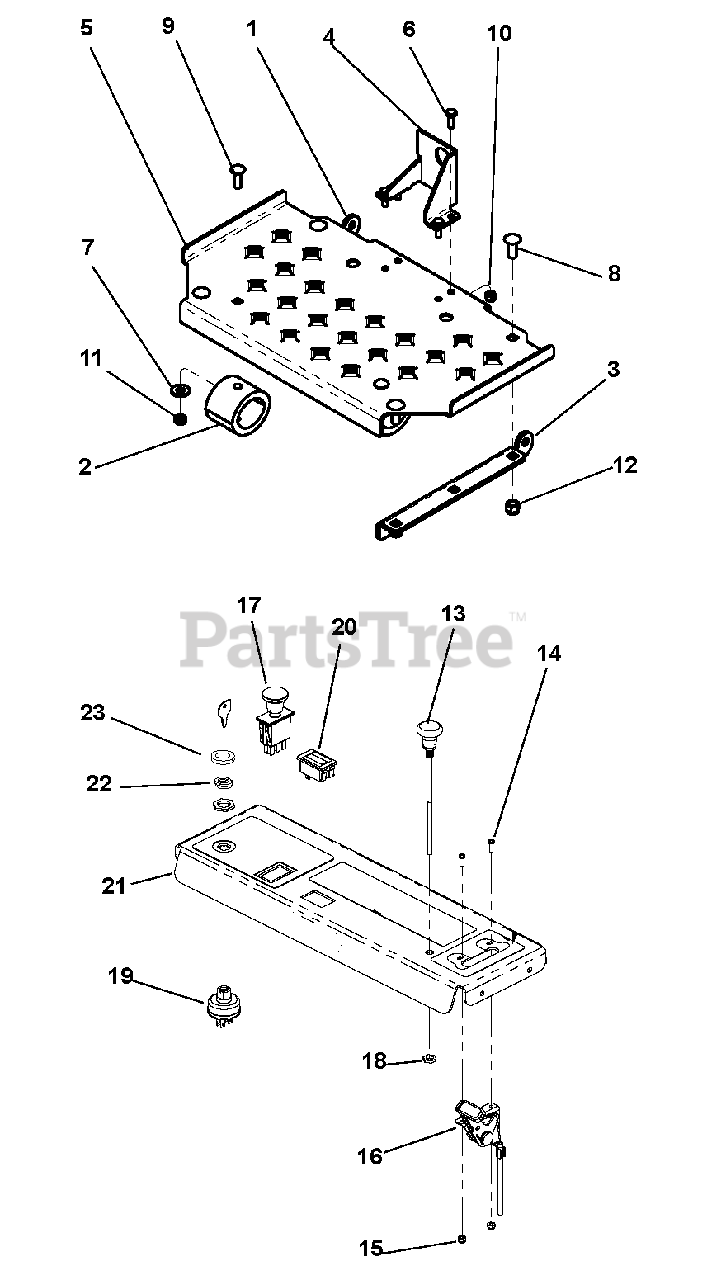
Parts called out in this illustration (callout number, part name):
1	Plate, Platform Tab
2	Bumper, Miner GBR-6
3	Plate, Platform Tab Left Hand
4	Anchor, Operator Presence Control
5	Platform
6	Bolt, Hex .25-20 x .75 Grade 5
7	Washer, Flat-Steel .38 x .875 x .083
8	Bolt, .375-16 x 1.00 Round Head Square Neck Grade 5
9	Bolt, .312-18 x 1.00 Round Head Square Neck Grade 5
10	Nut, Locking-Nylon .25-20
11	Nut, Locking-Nylon .312-18
12	Nut, Locking-Nylon .38-16
13	Cable, Choke
14	Screw, 8-32 x .50 Pan PHL Y
15	Nut, 8-32 Elastic Stop
16	Cable, Throttle
17	Switch, PTO Engagement
18	Nut, Hex .38-16
19	Switch, Key - 3 Position
20	Meter, Hour Digital w/Maintenance
21	Top, Console w/Decals
22	Nut, Panel .625-32
23	Cap, Ignition Switch
